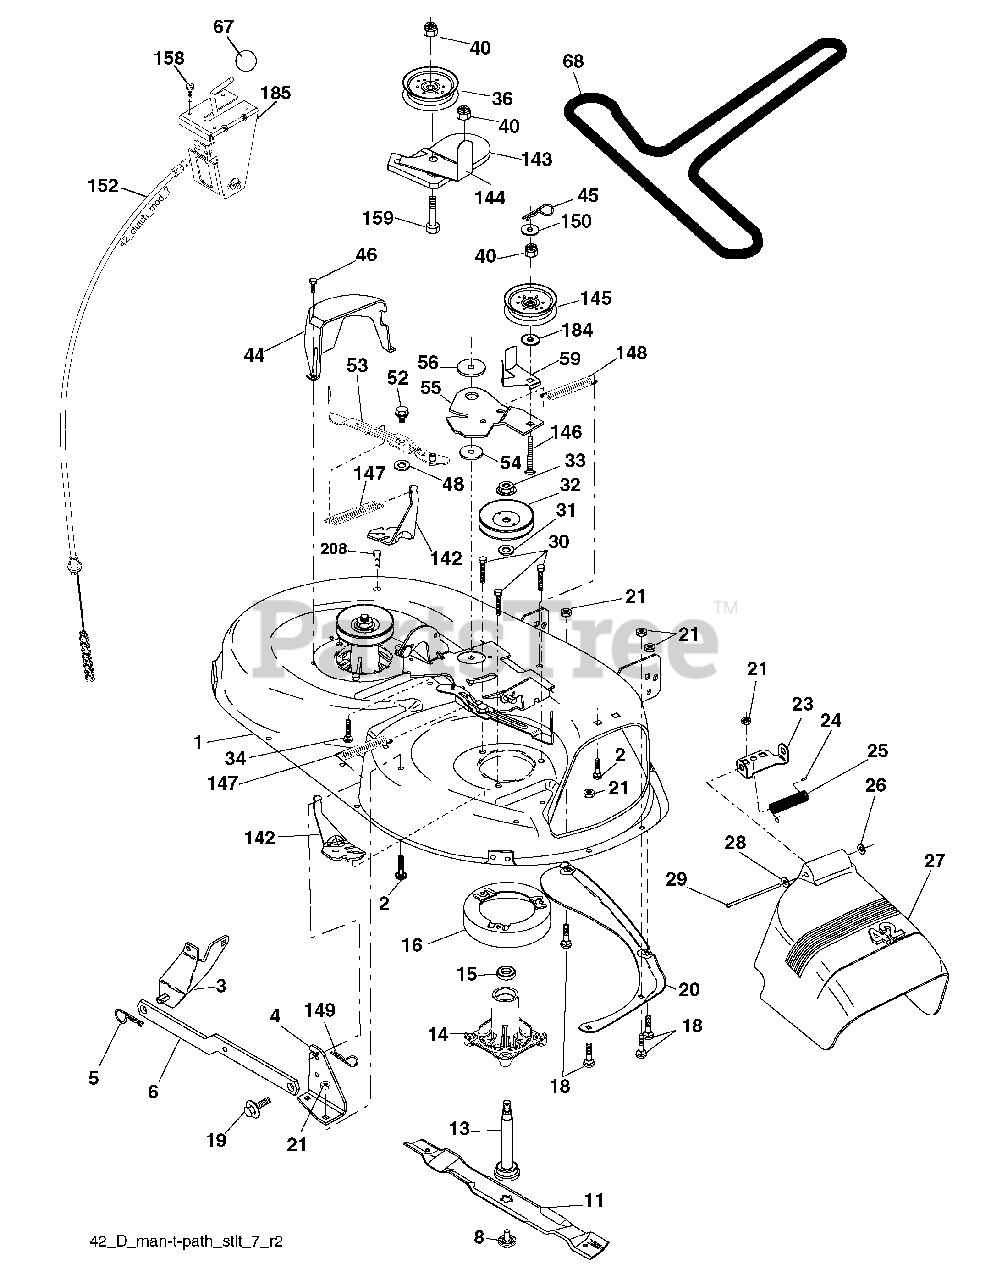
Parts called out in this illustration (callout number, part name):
1	Mower Deck Assembly, 42"
2	Bolt
3	Bracket Asm Fr. Sway Bar 3/42
4	Bracket Asm Deck 42" Sway Bar
5	Retainer Spring
6	Bar Sway Deck
8	Bolt/Washer Asm. 7/16-20 unf (The following Blades are available)
11	Blade Mower 42” Hi-Lift (for bagging and discharging)
11	Blade, Mulching 42” Std (for mulching mowers only)
11	Blade Mulching 42” Premium (For better wear when mulching)
13	Shaft As m. Mandrel
14	Housing Mandrel
15	Bearing, Ball, Mandrel
16	Stripper, Mandrel Deck
18	Bolt, Carriage 5/16-18 x 5/8
19	Bolt, Shoulder
20	Baffle, Vortex
21	Nut
23	Bracket, Deflector Mower 42"
24	Cap, Sleeve 80 x 112 Blk Mower
25	Spring, Torsion, Deflector 2 52
26	Nut, Push Phos & Oil
27	Shield, Deflector 42" Blk
28	Washer 11/32 x 5/8 x 16 Ga.
29	Rod, Hinge 42" 6 75 w/G
30	Screw Thdrol
31	Washer, Spacer Mower Vented
32	Pulley, Mandrel
33	Nut, Toplock
34	Bolt Carr SH 3/8-16 x 1-1/2 Gr.5
36	Pulley, Idler, Flat
40	Nut Lock 3/8-16
44	Guard, Mandrel, LH
45	Retainer
46	Screw, Thdrol 1/4-20 x 5/8 T
48	Washer, Hardened
52	Bolt, Shoulder 5/16-18 unc
53	Arm Assembly, Pad, Brake
54	Washer, Hardened
55	Arm, Idler
56	Spacer, Retainer
59	Guard TUV Idler
67	Knob Round
68	V-Belt, 42" Mower
142	Anchor Spring Brake Mower
143	Bracket Arm Idler 42"
144	Keeper Belt 42" Clutch Cable
145	Pulley Idler Flat
146	Bolt Carriage Idler
147	Spring Extension
148	Spring Return Idler
149	Retainer Spring Yellow
150	Washer 9/32 x 3/4 x 10 Ga.
152	Clutch Cable 42"
158	Screw Hex Thd Cut 1/4-20 x 1/2
159	Bolt Rdhd Sqn 3/8-16 unc x 1-3/4
184	Washer 13/32 x 7/8 x 10 Ga.
185	Head Asm Cable Clutch
208	Screw 3/8-16 x 1/2
208	Mandrel Assembly
208	Replacement Mower, Complete
